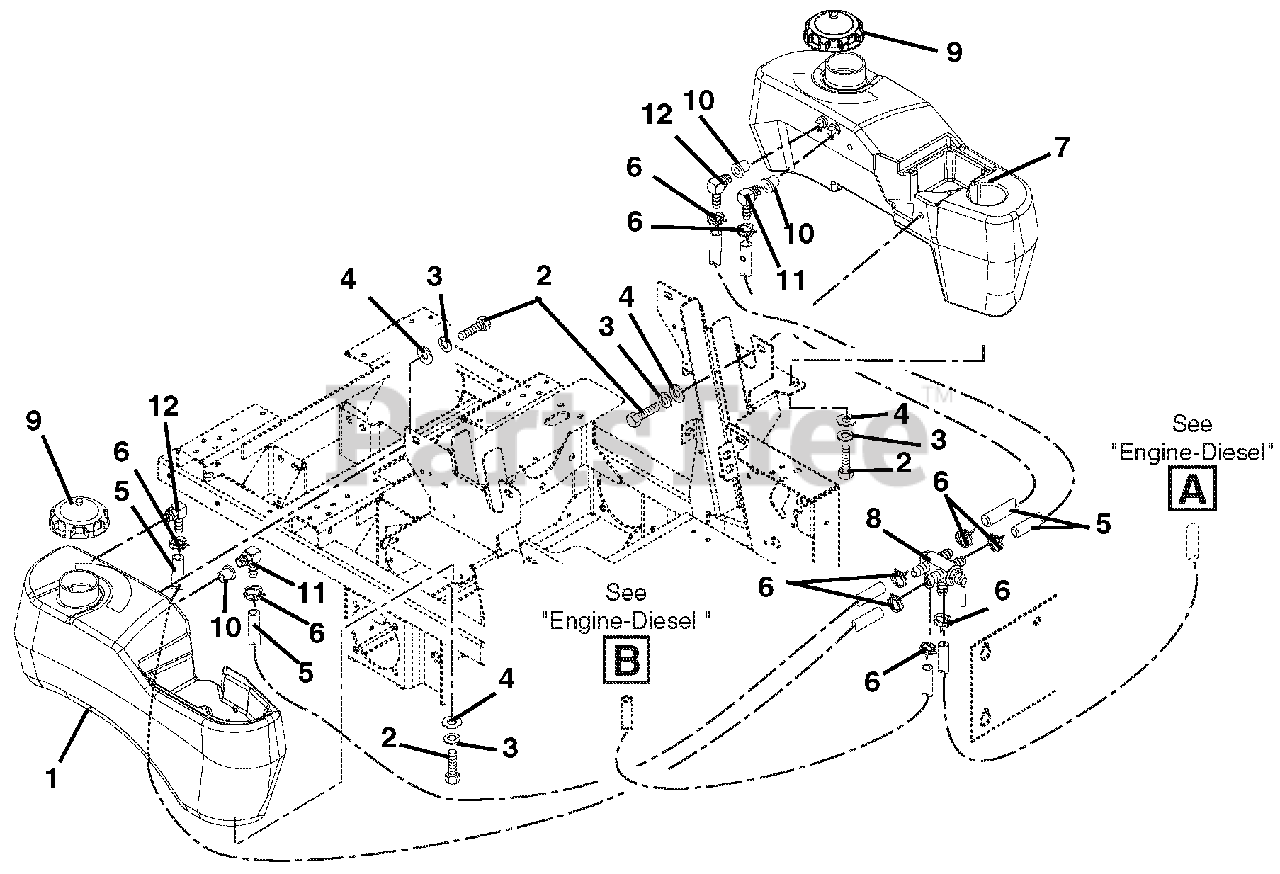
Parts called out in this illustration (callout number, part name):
1	Tank, Fuel-Right Hand
2	Bolt, Hex .31-18 x .75 Grade 5
3	Washer, Locking .31 x .078
4	Washer, Flat Steel .38 x .875 x .083
5	Hose, .31 ID
6	Clamp, Hose Wire .52/.55
7	Tank, Left Hand Fuel (EYE-Q) 200 Series-EFI
8	Valve, Fuel
9	Cap, Fuel
11	Fitting, Tank
12	Fitting, Tank
